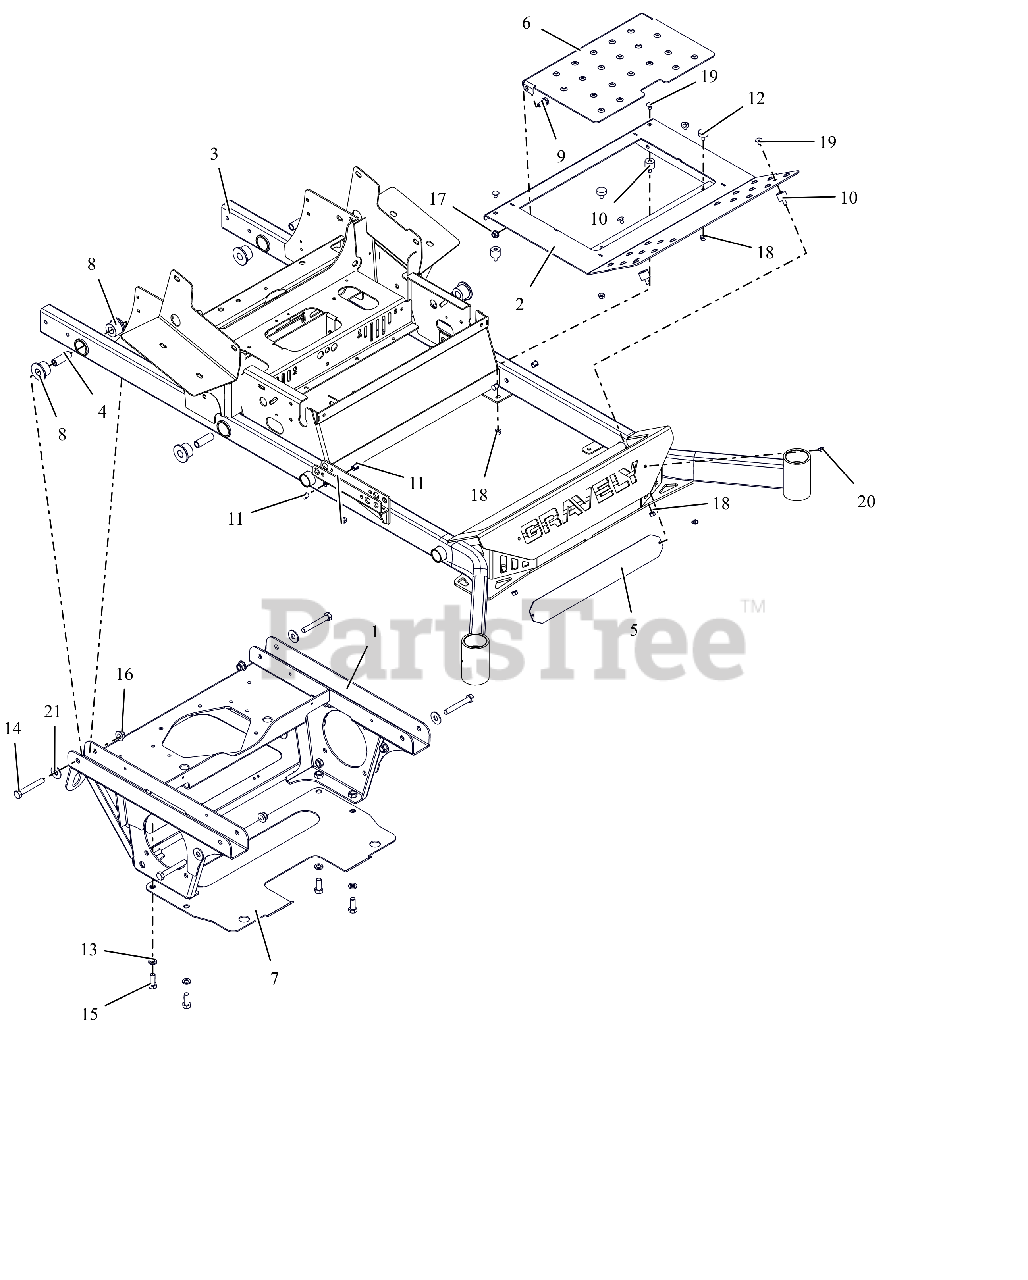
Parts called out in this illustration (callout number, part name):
1	PT200/400 AXLE/ENG FRM WMT-RED
2	FOOTPLATE WLDMT W/SAFETY DECAL
3	72" PT200/400 FRAME W/DECALS
4	BSHG-SLV .50X.75X2.23
5	BUMPER LOGO BACKING PLATE -BLK
6	INSPECTION PANEL W/SAFTY DECAL
7	PLATE-TRANSMISSION SKID
8	BSHG-FLG .75X1.51X1.13X2.0 URE
9	BLT,SHLDR EP .38-16X.30 HEX YZ
10	BUMPER,STUD MNTD W/FEMALE INSR
11	PLUG, HOLE .50
12	BUMPER, RUBBER
13	WSHR,LK-REG .500X.125 ZCC
14	BLT, HEX .50-13X3.50 G5 ZCC
15	BLT,HEX .50-13X1.25 G5 ZCC
16	NUT,NYL-FLG .50-13 GF ZCC
17	NUT,NYL-FLG .38-16 GF ZCC
18	NUT,SPNLK-FLG .31-18 G5 ZCC
19	BTL,RHSN .313-18 X 0.5 G5 ZCC
20	SCR-TAP .25-20X.50 HWH ZCC
21	WSHR,FLT .563X1.375X.109 ZCC
